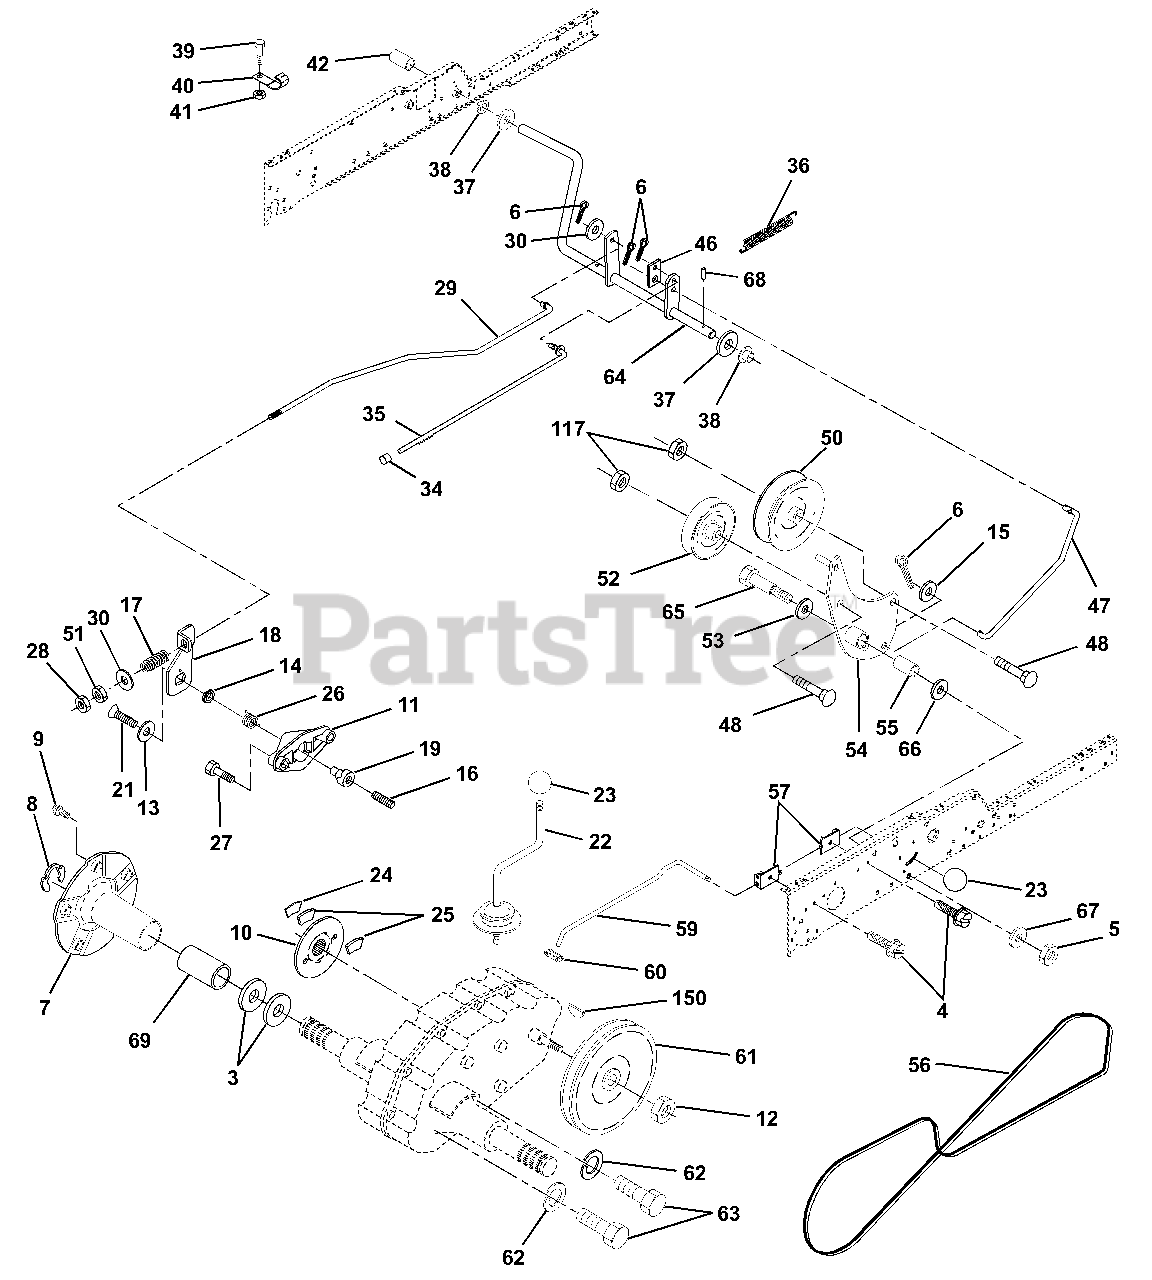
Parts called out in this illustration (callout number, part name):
3	Washer, Thrust, Axle
4	Screw Thdrol 5/16-18 x 3/4
5	Nut, Crownlock 3/8-16
6	Pin, Cotter
7	Wheel, Hub Assembly
8	Klip, Ring
9	Bolt, Hub
10	Disc, Brake
11	Yoke, Brake Disc
12	Nutlock 1/2-20 Unf
13	Washer, Special
14	Bushing
15	Washer 13/32 x 13/16 x 16 Ga.
16	Set, Screw 1/4-28 x 3/4
17	Spring
18	Lever, Brake
19	Cam, Brake Disc
21	Screw, Flat Head 1/4-28 x 3/4
22	Gearshift, Lever Assembly
23	Knob
24	Support, Puck Brake
25	Puck, Brake Top
26	Spring, Return
27	Screw, Hex Wsh Thd. 5/16-18 x 1-3/4
28	Nut, Hex Jam 3/8-16
29	Brake, Rod
30	Washer 13/32 x 1 x 16 Ga.
34	Cap, Plunger
35	Rod, Parking Brake
36	Spring, Drive Ground
37	Washer 25/32 x 1-1/4 x 16 Ga.
38	Nyliner
39	Screw, Fin. #10-24 x 1
40	Actuator, Interlock Switch
41	Nut Centerlock 10-24-Umc
42	Cover, Pedal
46	Retainer, Spring
47	Clutch Rod
48	Bolt, Carriage 3/8-16 x 1-1/2 Gr. 5
50	Pulley, Idler, Flat
51	Nut, Crownlock 3/8-16 UNC
52	Pulley, Idler, Grooved
53	Washer, Hardened
54	Clutch, Arm Assembly
55	Bearing, Idler
56	V-Belt
57	Bracket, Shift Rod, Hi-Lo
59	Shift Rod, Hi-Lo
60	Spring Clip, Connecting Link
61	Pulley, Transaxle
62	Washer, Lock 7/16
63	Bolt, Fin Hex 7/16-14 x 1-1/4
64	Shaft, Clutch/Brake Pedal
65	Bolt, Shoulder
66	Washer, Hardened
67	Washer, Flat
68	Pin, Roll
69	Hub, Cover
117	Nut, Lock Flg. 3/8-16 Unc
150	Key, Woodruff
